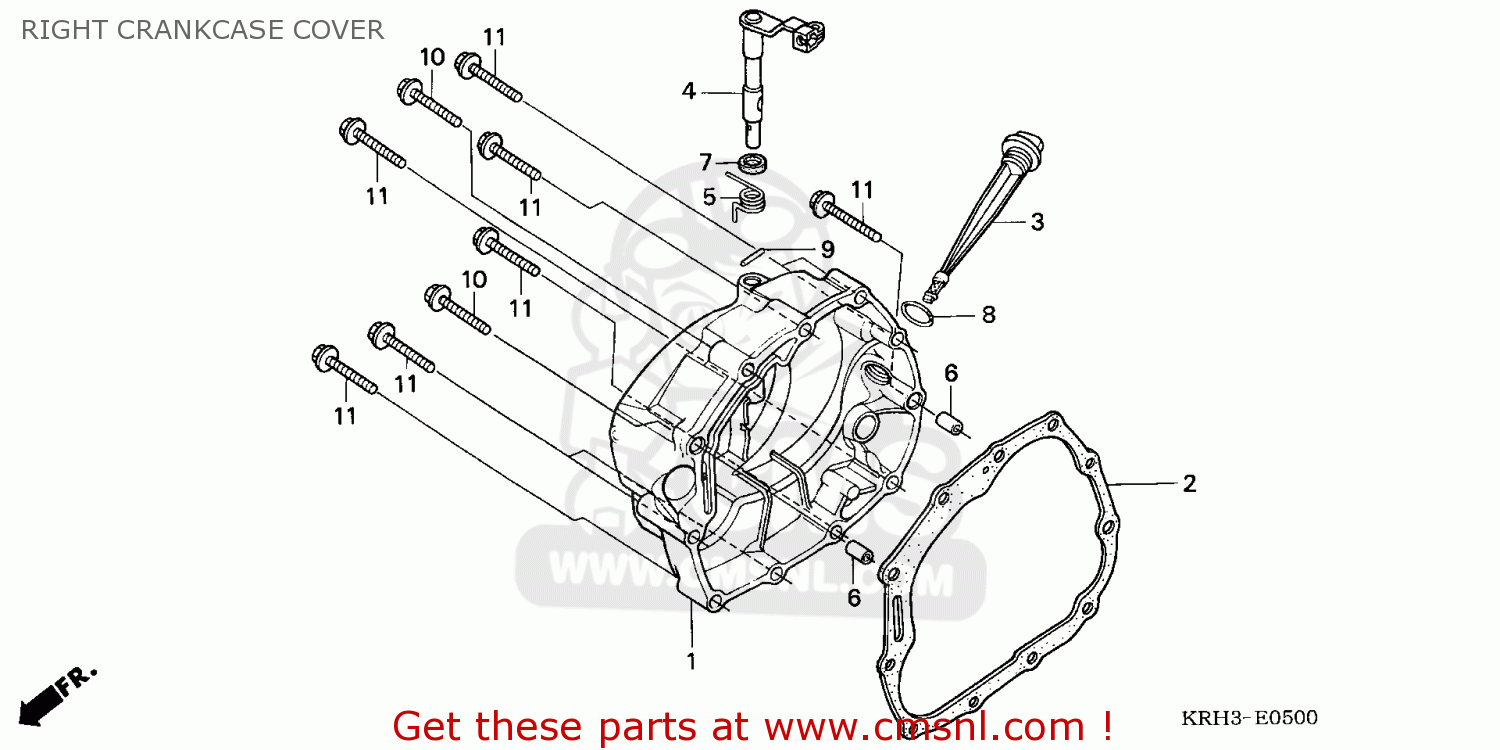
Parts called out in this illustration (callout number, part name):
1	COVER COMP,R CRAN
2	GASKET,R COVER (NAS)
3	GAUGE,OIL LEVEL
4	LEVER,CLUTCH
5	SPRING,CLUTCH LEV
6	DOWEL PIN,8X14
7	OIL SEAL,12X22X5
8	O-RING,18X3
9	PIN,SPG. 3X10
10	BOLT,FLANGE SH6X3
11	BOLT,FLANGE SH6X4
